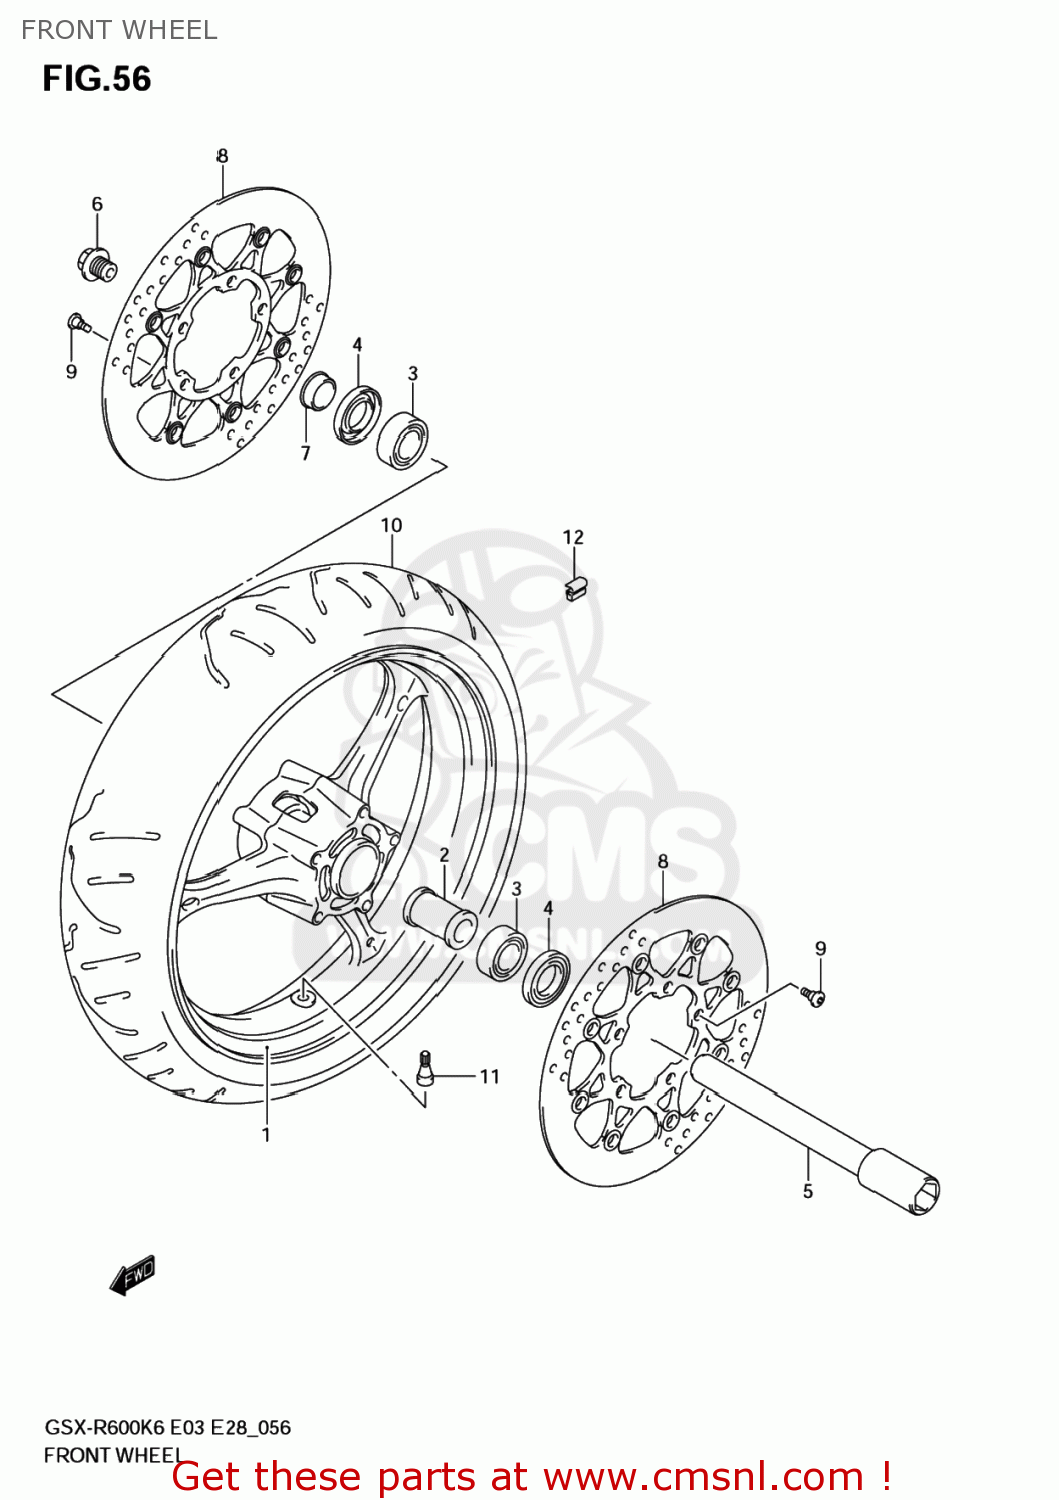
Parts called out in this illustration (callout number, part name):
1	WHEEL,FRONT(17
2	SPACER,FR HUB BEARING
3	BEARING(25X52X15)
4	SEAL,OIL(32X52X7)
5	AXLE,FRONT
6	BOLT,FRONT AXL
7	SPACER,FRONT A
8	DISC,FR BRAKE
9	BOLT(8X21)
10	TIRE,FR(120/70 ZR17M/C 58W)
11	VALVE ASSY,WHEEL RIM(TR412)
12	BALANCER, WHEEL NO.1
